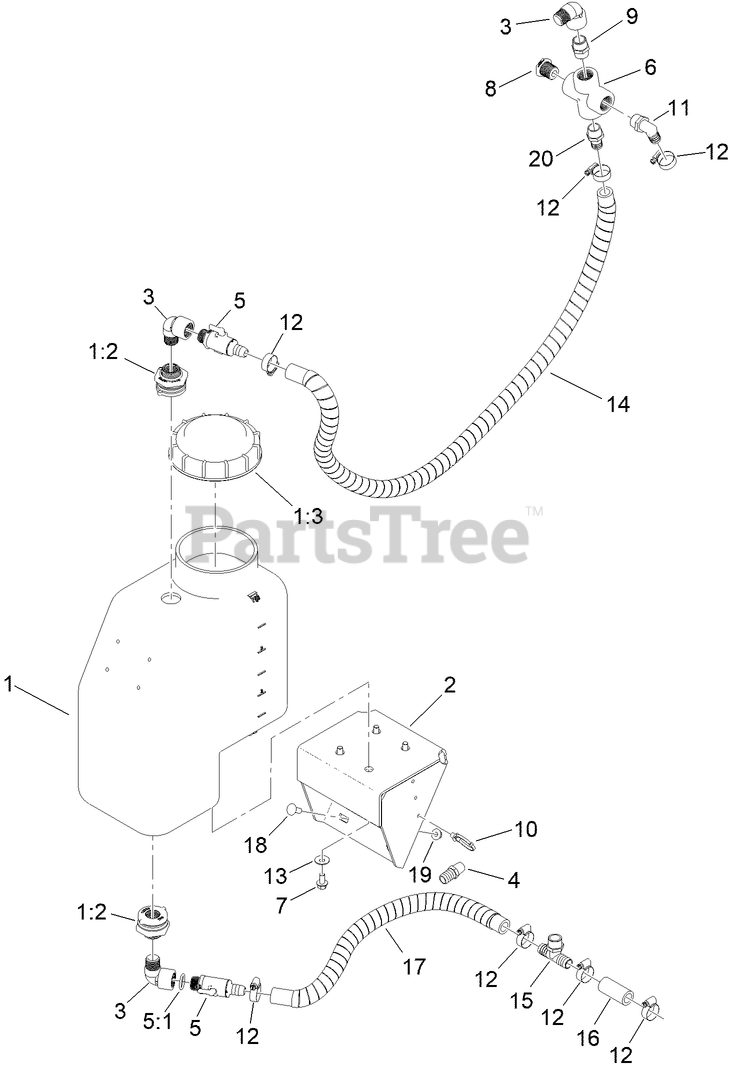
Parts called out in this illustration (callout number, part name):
1	ASM-TANK, 7GAL
1:2	FITTING-BULKHEAD
1:3	CAP-TANK, SPRAY
2	MOUNT-TANK, 7 GAL
3	ELBOW-90 DEG
4	FITING-STRAIGHT
5:1	O-RING, -213
6	FITTING-CROSS
7	SCREW-HHF
8	FITTING-PLUG
9	FITTING-NIPPLE
10	CLIP-TIE
11	FITTING-ELBOW, 90
12	CLAMP-HOSE
13	WASHER-SPRING
14	HOSE-SPRAY, WRAPPED
15	FITTING-TEE
16	HOSE-SPRAY
17	HOSE-SPRAY, WRAPPED
18	SCREW-CARR
19	NUT-HEX FLANGE
20	HOSEBARB
